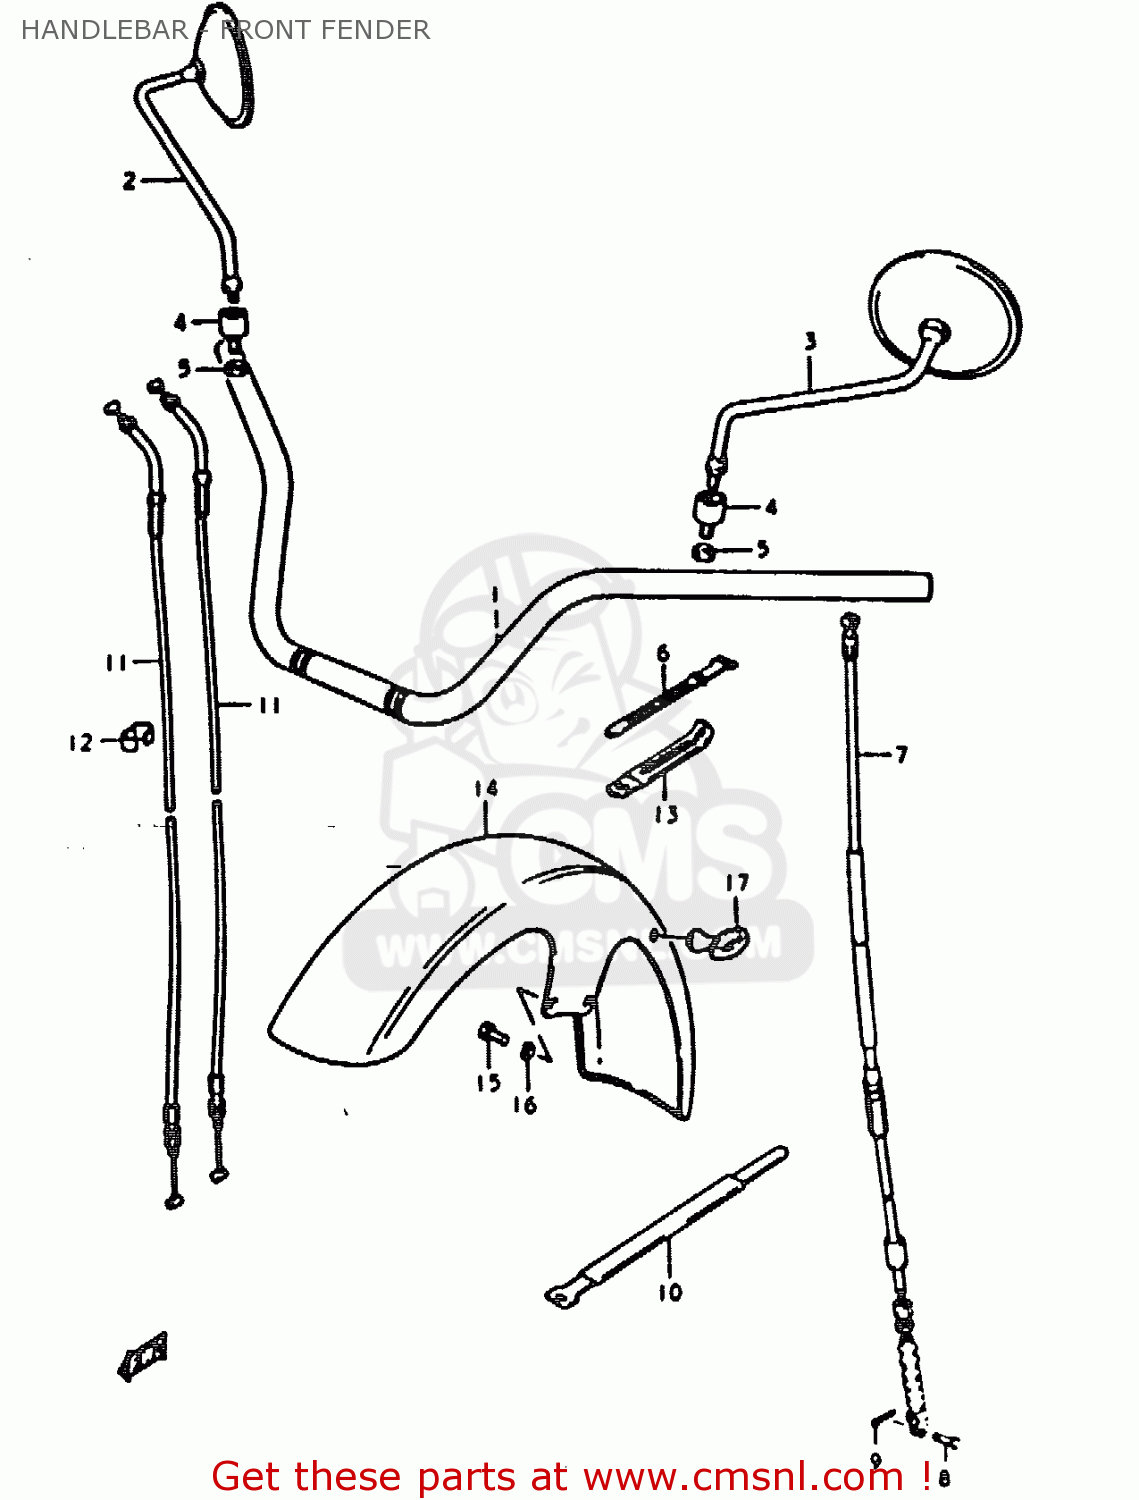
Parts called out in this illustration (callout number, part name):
1	HANDLEBAR
2	MIRROR ASSEMBLY,RIGHT
3	MIRROR ASSEMBLY,LEFT
4	CUSHION,REAR VIEW MIRROR
5	NUT
6	CLAMP(L:120)
7	CABLE ASSY,CLUTCH
8	PIN(L:15)
9	PIN
10	CLAMP
11	CABLE ASSY,THROTTLE
12	CLIP
13	CLAMP
14	FENDER,FR
15	BOLT
16	LOCK WASHER
17	GUIDE,CABLE
